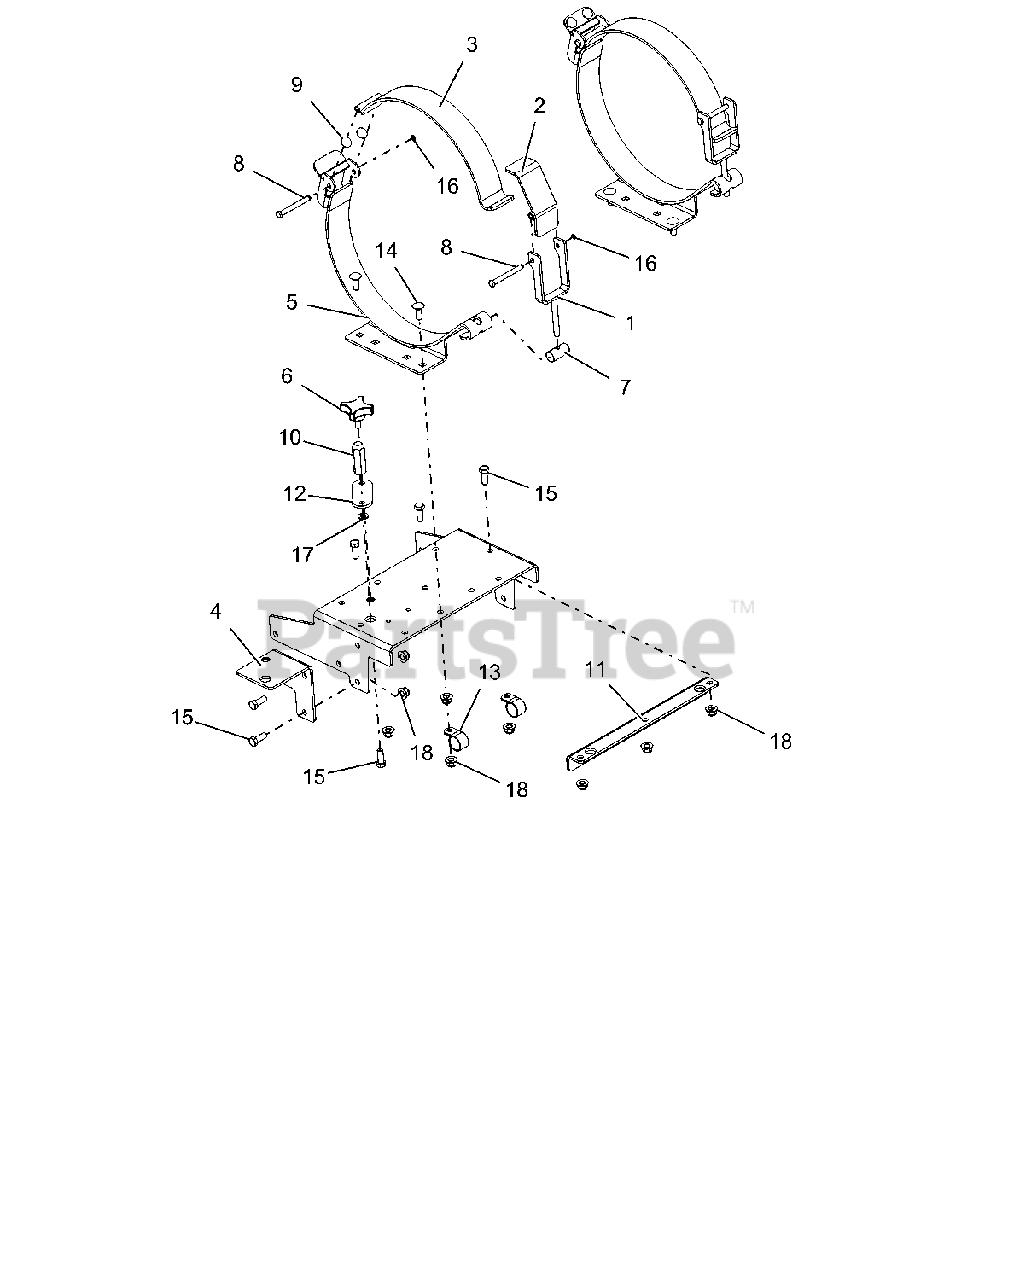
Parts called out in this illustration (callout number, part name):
1	WLDMT, TANK CLAMP TOGGLE
2	WLDMT, TANK TOGGLE HANDLE
3	WLDMT, UPPER LP TANK CLAMP
4	BRKT, POST WLDMT
5	WLDMT, CLAMP LP TANK-BLACK
6	KNOB, 3/8-16 x .75
7	PIVOT, LP CLAMP HANDLE
8	PIN, LP CLAMP
9	MAGNET, .75X.060, LP CLAMP
10	POST, INDICATOR LP TANK
11	STIFFENER, TANK BED
12	PLATE, PIN MOUNT
13	CLAMP, CUSHIONED STEEL REV
14	BLT-RDHDSQNK .38-16X1.00 G5 YWZC
15	BLT-HEX .38-16X1.00 GR5 YWZC
16	RG-RTNG-EXT .312X.025
17	WSHR-LK .38X.094 REG YWZC
18	NUT-LK-NYL-FLG .38-16 YWZC
